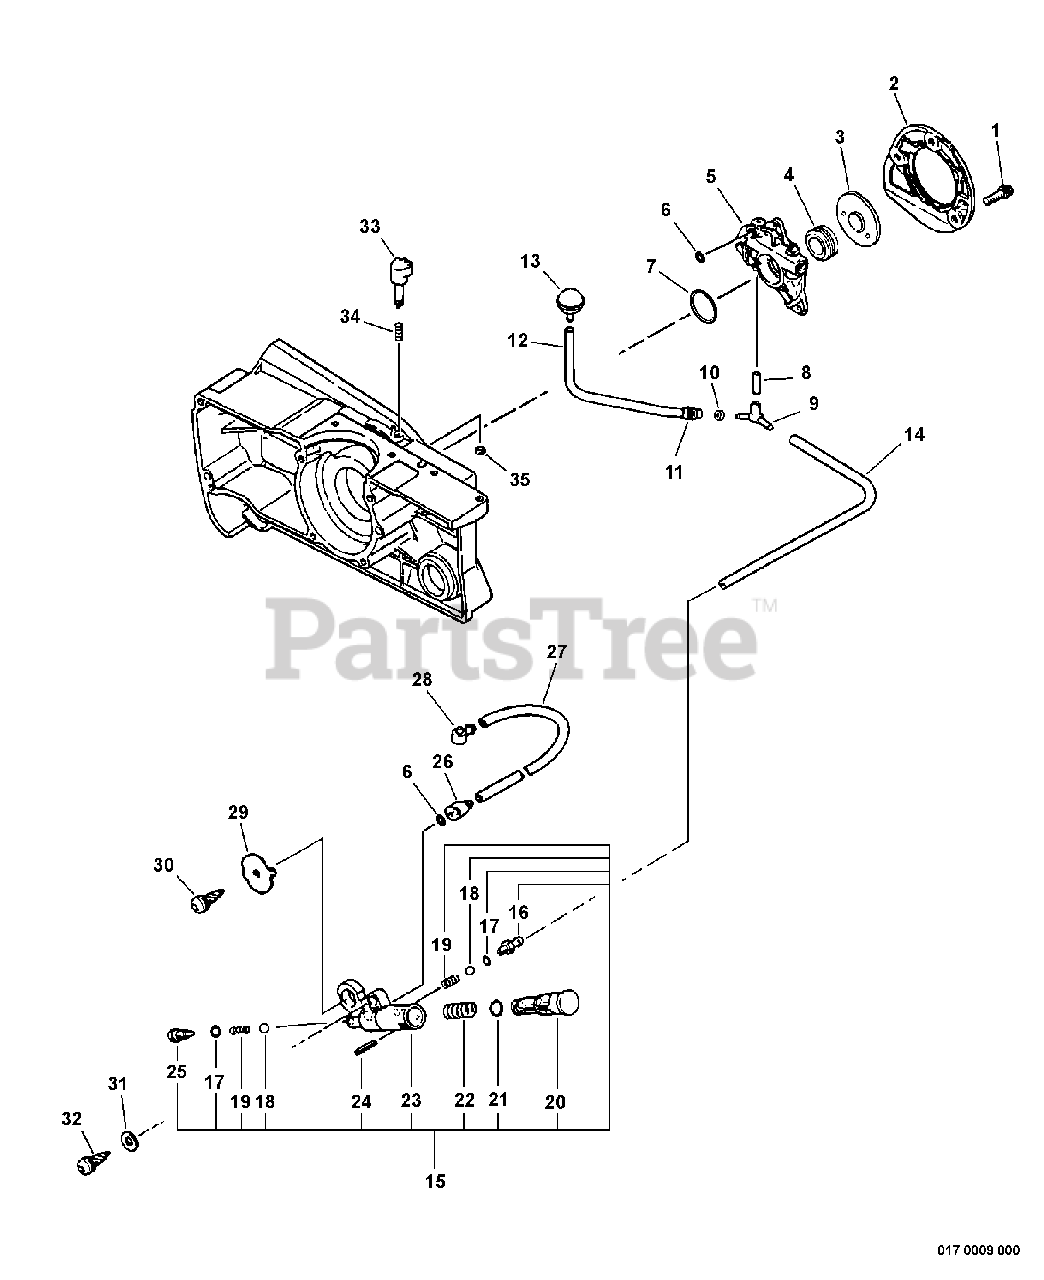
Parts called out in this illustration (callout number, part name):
1	BOLT 4×12
2	COVER, OIL PUMP - ORANGE
3	WASHER 12
4	GEAR, WORM
5	AUTO-OILER ASSY
6	O-RING 3
8	PIPE, OIL 3×6×20
9	CONNECTOR, PIPE
10	CLIP Ø6.5 MM
12	PIPE, OIL
13	FILTER, OIL
14	PIPE, FUEL 3×6×200
15	OIL PUMP ASSY - ORANGE
16	CONNECTOR, PIPE
18	VALVE, BALL
19	SPRING, COMPRESSION
20	PISTON, OIL PUMP - ORANGE
21	O-RING 7 MM
23	BODY, OIL PUMP
24	PIN, SPRING 2×16
25	ADAPTOR, OIL PUMP
26	CONNECTOR, PIPE
27	PIPE 3×6×125 BLACK
28	CONNECTOR, PIPE
29	BRACKET, OIL PUMP
30	SCREW 4×10
31	WASHER 5.5×12×0.8
32	SCREW 5×20
35	E-RING 3
